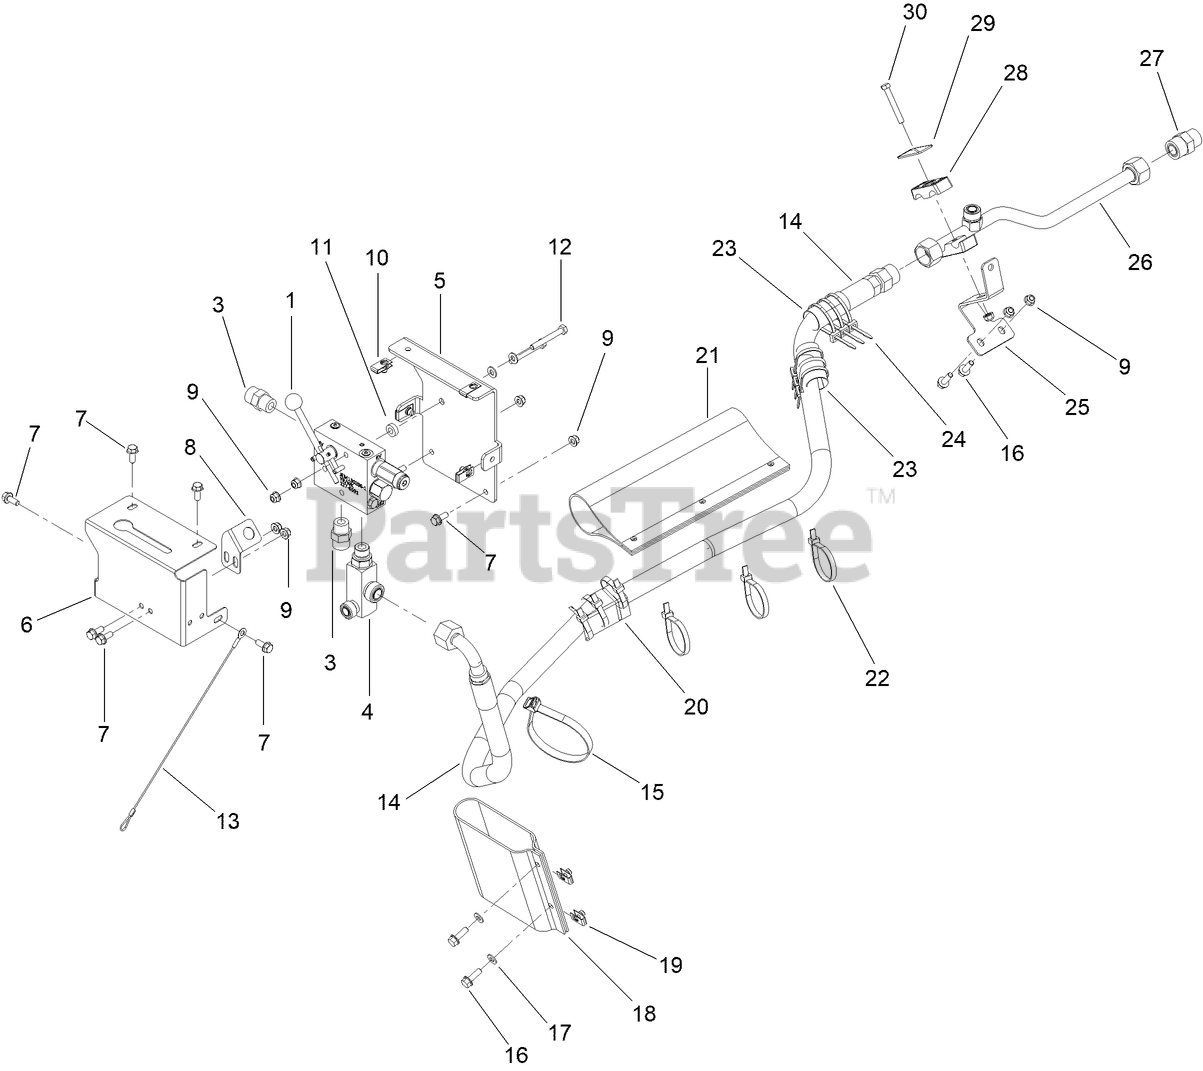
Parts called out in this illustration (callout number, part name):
1	VALVE-CONTROL, VIBE PLOW
3	CONNECTOR (10S-10O)
4	CONNECTOR (10S-10O-12O)
5	MOUNT PLATE-VALVE
6	BRACKET-COVER
7	SCREW-HHF
8	PLATE-SENSOR (PAINTED)
9	NUT-HF, NI
10	NUT-U TYPE
11	SPACER
12	SCREW-HH
13	LANYARD LOOP/EYE 14"
14	HOSE (12ORSM-12OFX90S-68"-3000)
15	CABLE TIE (1/2") 20" LG
16	SCREW-HHF
17	WASHER-PLAIN
18	BOOT-HOSE
19	NUT-CLIP, U
20	PROTECTOR-HOSE
21	BOOT-HOSE
22	TIE-CABLE
23	PROTECTOR-HOSE
24	TIE-CABLE
25	BRACKET-TUBE
26	HARDLINE (-12 RETURN TO COOLER)
27	CONNECTOR (12S-12O)
28	CLAMP-TUBE
29	PLATE-COVER
30	SCREW-HH
